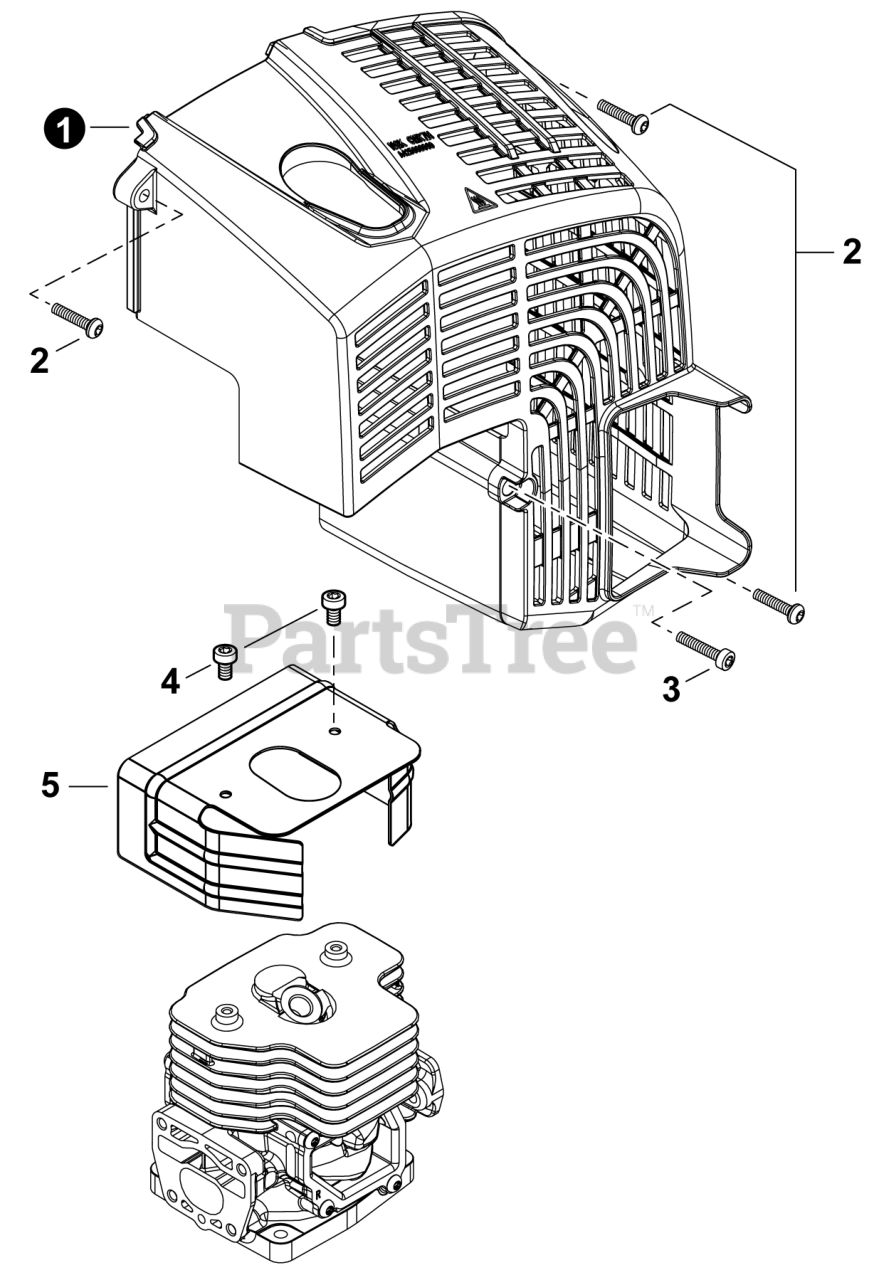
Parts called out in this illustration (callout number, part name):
1	COVER, ENGINE
2	BOLT, TORX 5x20
3	BOLT 5x20
4	BOLT, TORX 4x8
5	COVER, CYLINDER
